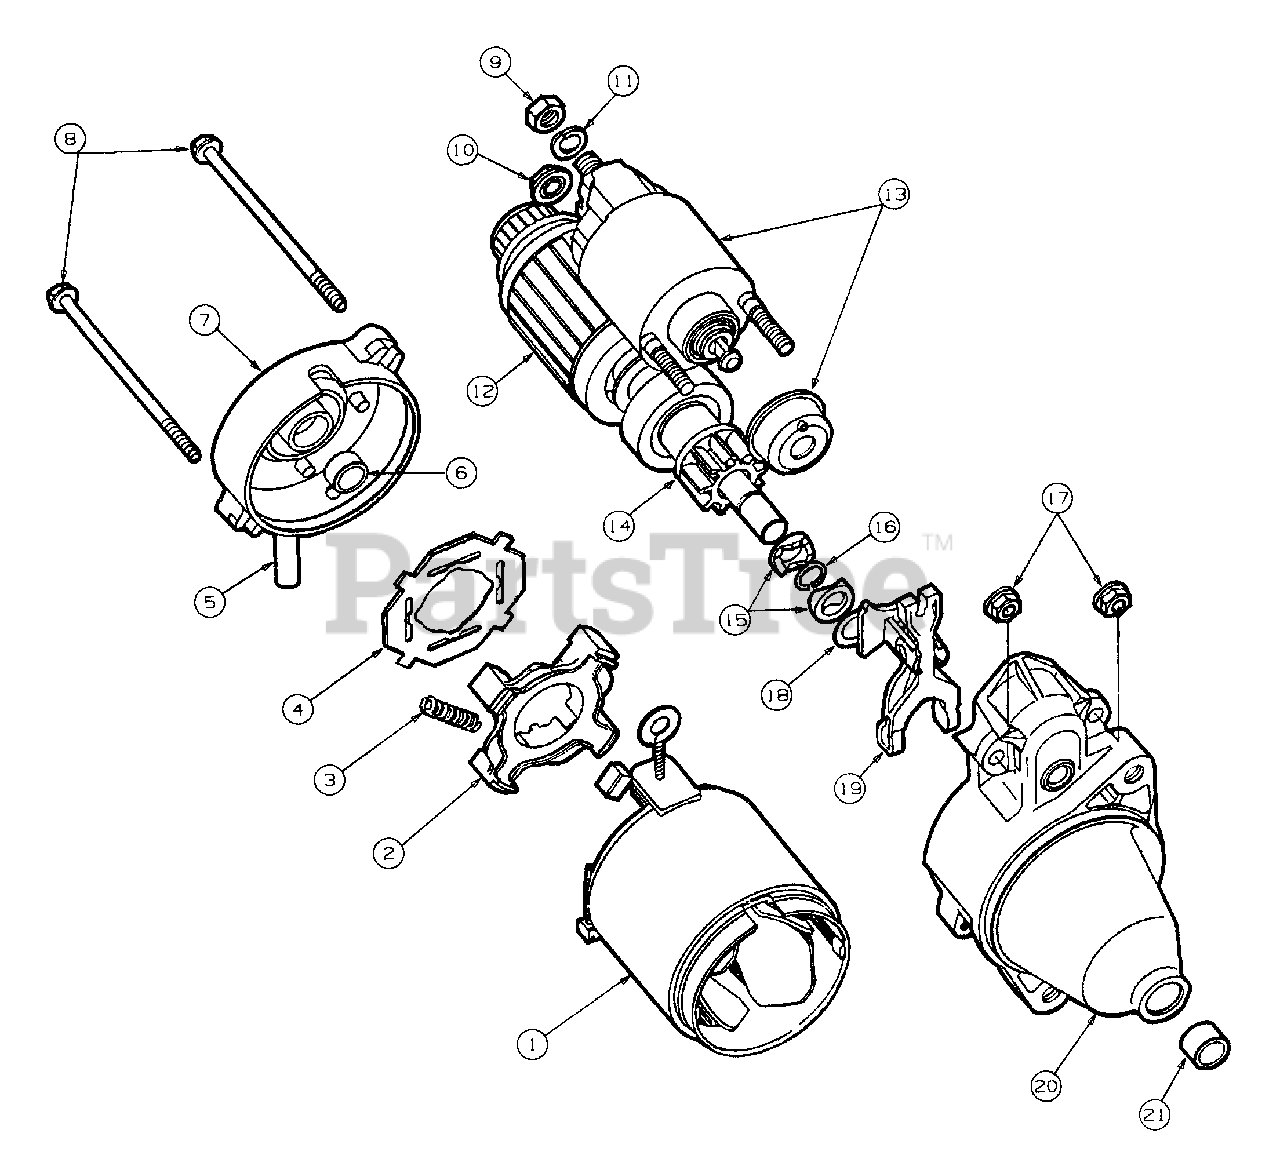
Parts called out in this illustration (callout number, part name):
1	Frame, Starter
2	Holder, Brush
3	Spring, Brush
5	Hose, Drain
6	Bearing, Oilless
7	Frame Assy, End
8	Bolt, Through
11	Washer. Spring
12	Armature, Starter
13	Switch, Magnetic
15	Nut, Pinion Stop
18	Washer, Plate
19	Lever, Starter Drive
20	Housing, Starter
21	Bearing, Oilless
